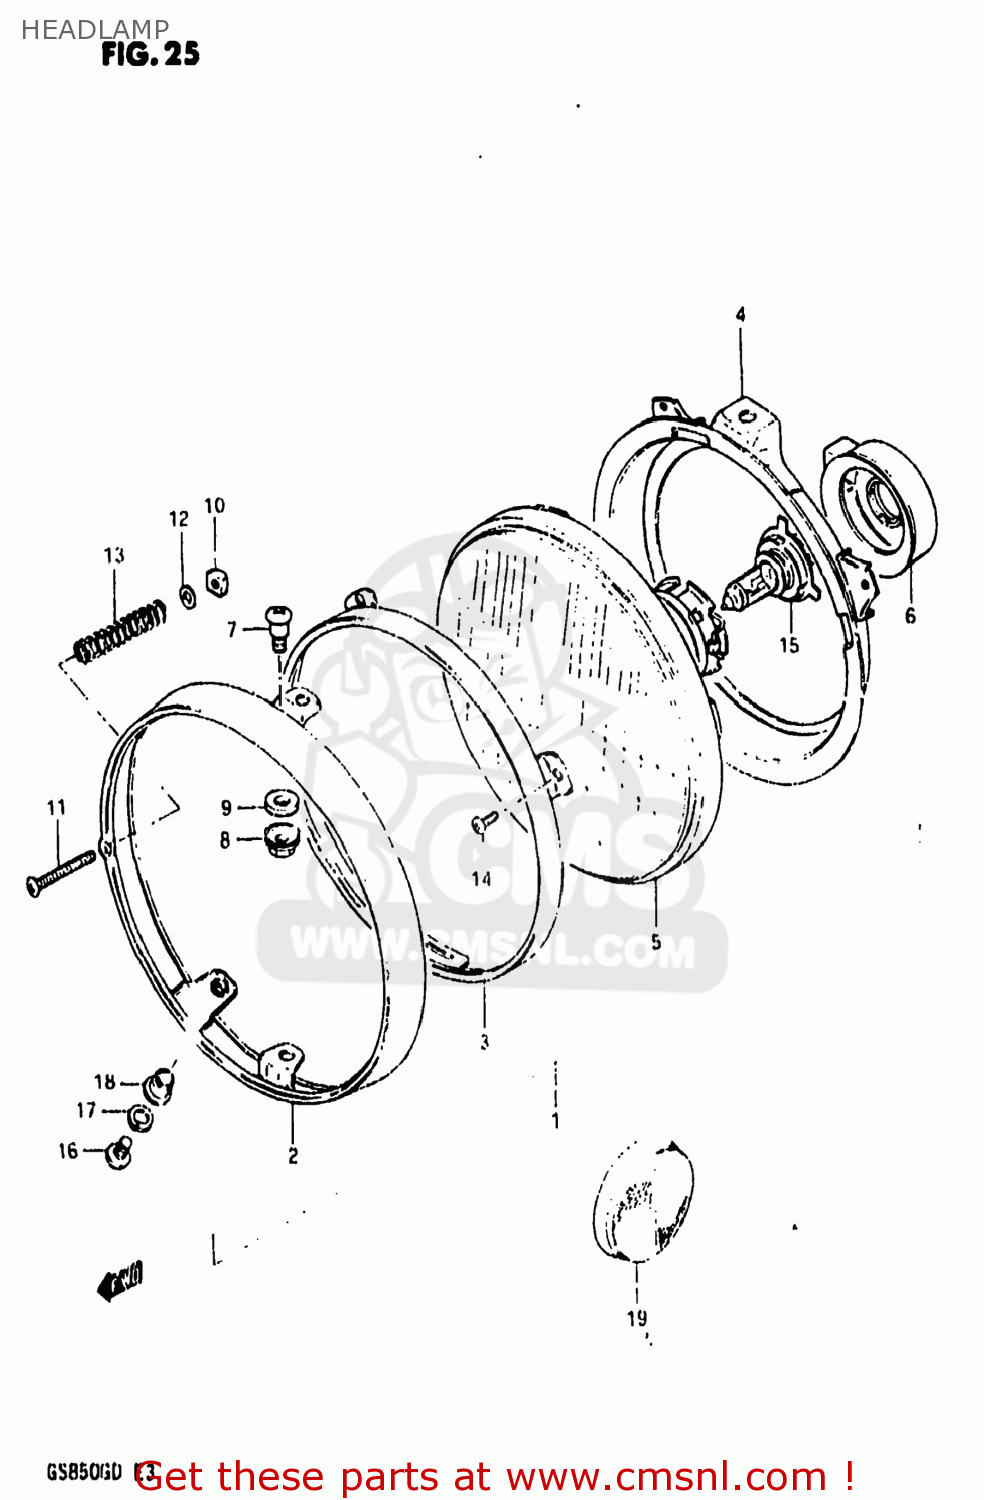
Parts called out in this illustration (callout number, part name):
1	HEADLAMP ASSEMBLY
2	RIM
3	RETAINER
4	RING,HEADLAMP UNIT
5	LAMP UNIT
6	COVER,HEADLAMP SOCKET
7	SCREW
8	NUT,ADJUSTING
9	SPACER
10	NUT
11	SCREW
12	WASHER
13	SPRING,HEADLAMP ADJUST
14	SCREW
15	BULB(12V60/55W,H4)
16	SCREW
17	WASHER,LOCK
18	WASHER
19	REFLEX REFLECTOR,RR
